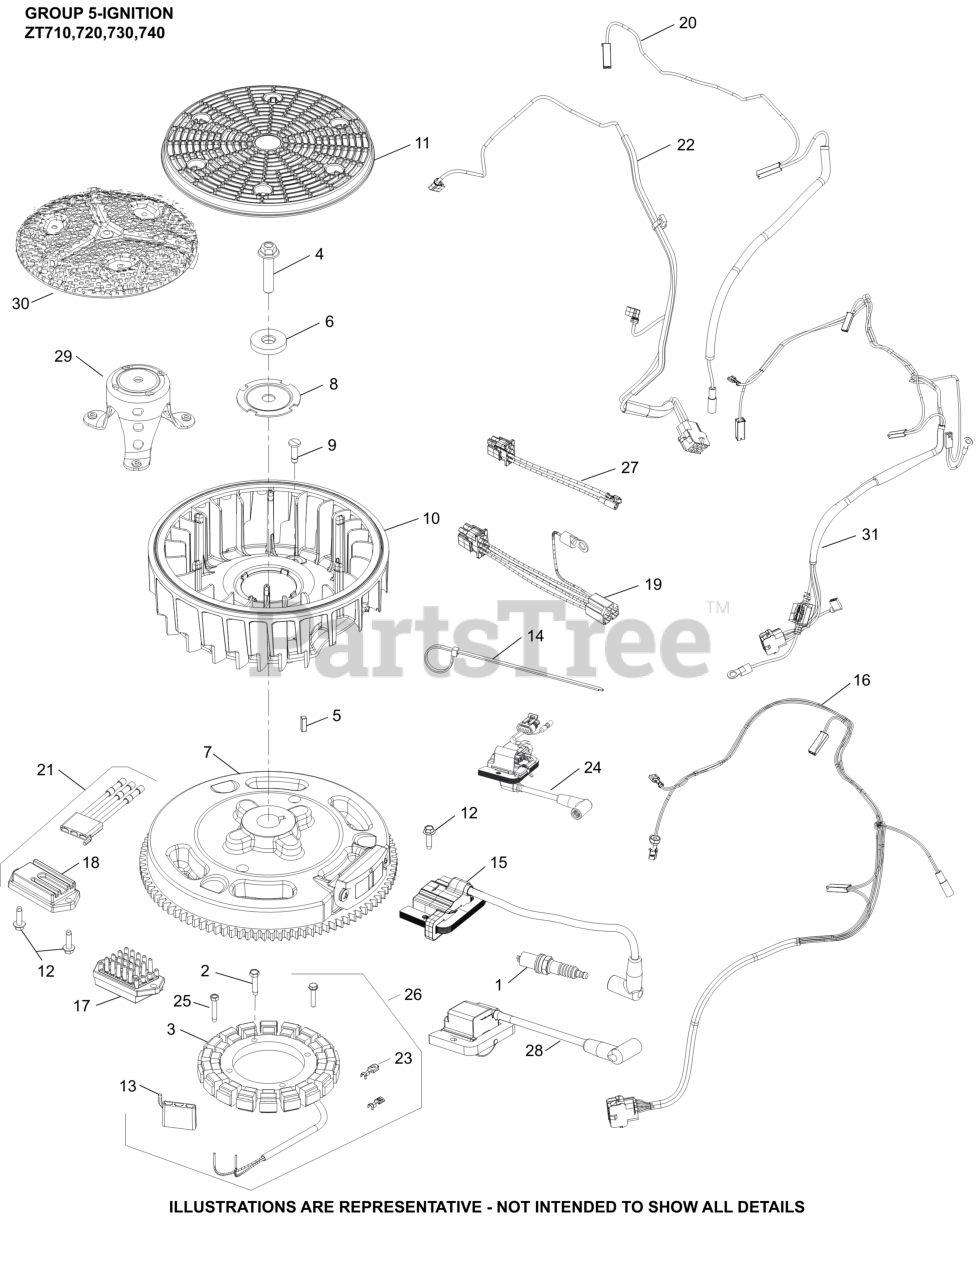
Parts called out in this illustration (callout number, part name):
1	SPARK PLUG, RFI
2	SCREW, THREAD FORMING
3	KIT, 15 / 20 AMP STATOR
4	SCREW, HEX FLANGE
5	KEY, SQUARE
6	WASHER, FLAT
7	FLYWHEEL ASSEMBLY
8	PLATE, FAN MOUNTING
9	RETAINER, FLYWHEEL FAN
11	SCREEN, GRASS
12	SCREW, THD FRM-USE 25 086 473-S
13	CONNECTOR
17	REGULATOR/RECTIFIER 12/15A HALF-WAVE STD
28	MODULE, MAGNETO DIGITAL IGNITION
NI	HARNESS, WIRING ASSEMBLY
